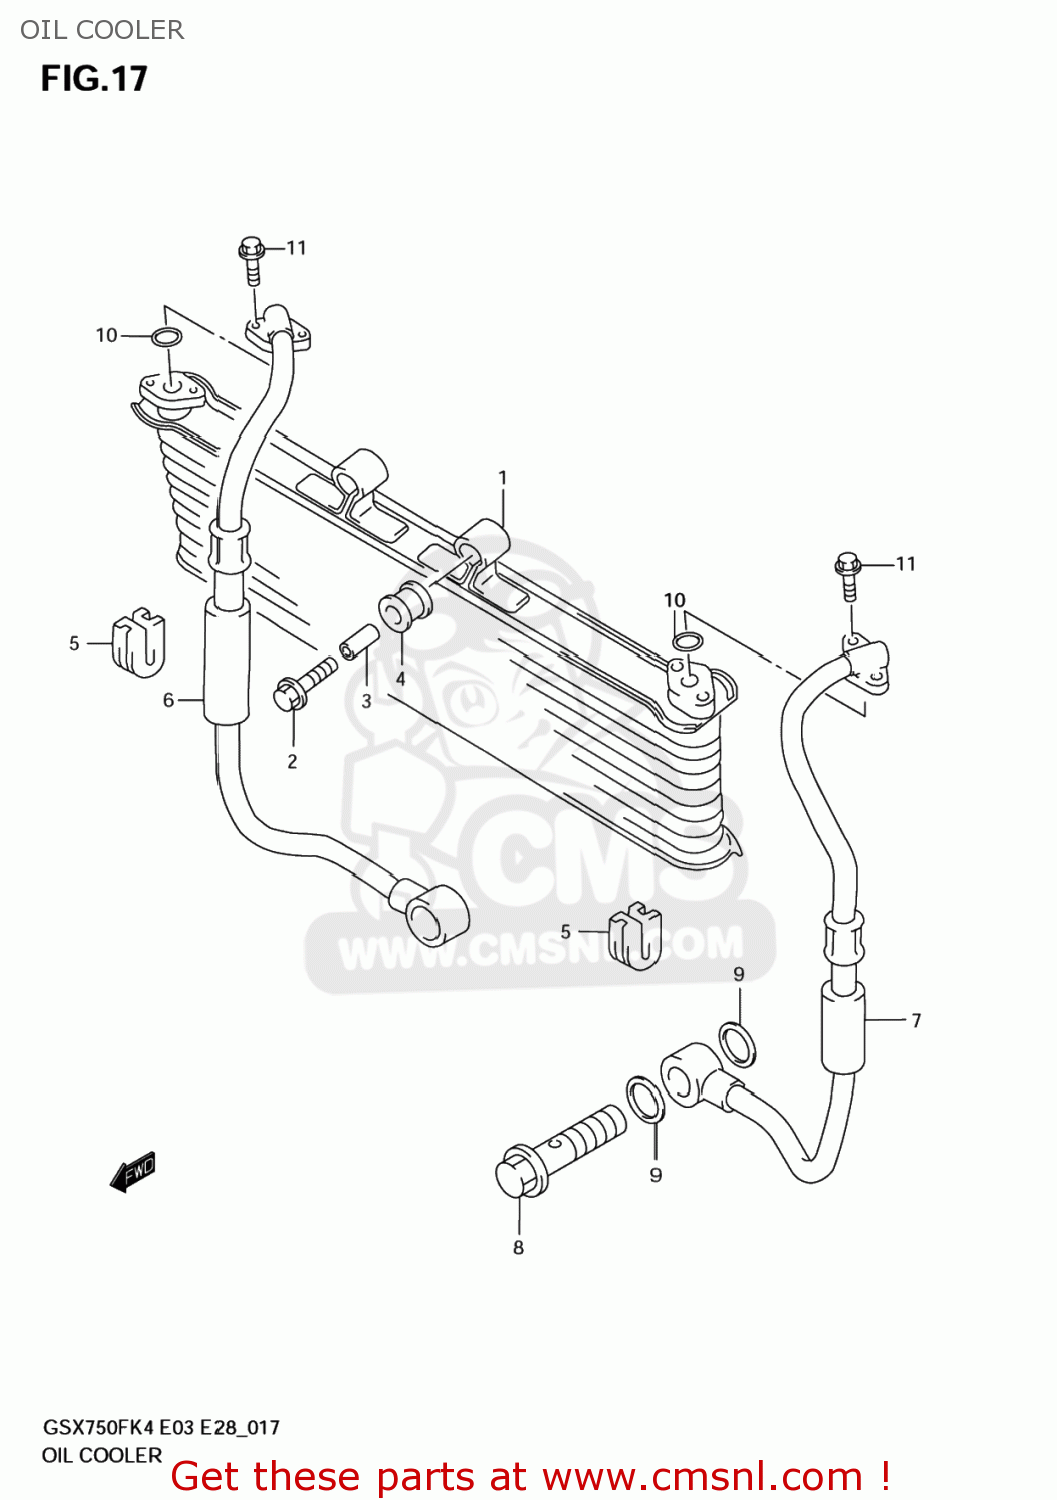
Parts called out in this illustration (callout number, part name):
1	COOLER ASSY,OIL
2	BOLT(8X40)
3	SPACER(8.5X12X25)
4	CUSHION,OIL COOLER NO.1
5	CUSHION,OIL COOLER NO.2
6	HOSE,OIL COOLER,R
7	HOSE,OIL COOLER,L
8	BOLT UNION
9	GASKET(16X22X2) (NAS)
10	O RING(D:2.4,ID:11.8)
11	BOLT,OIL FILLE
